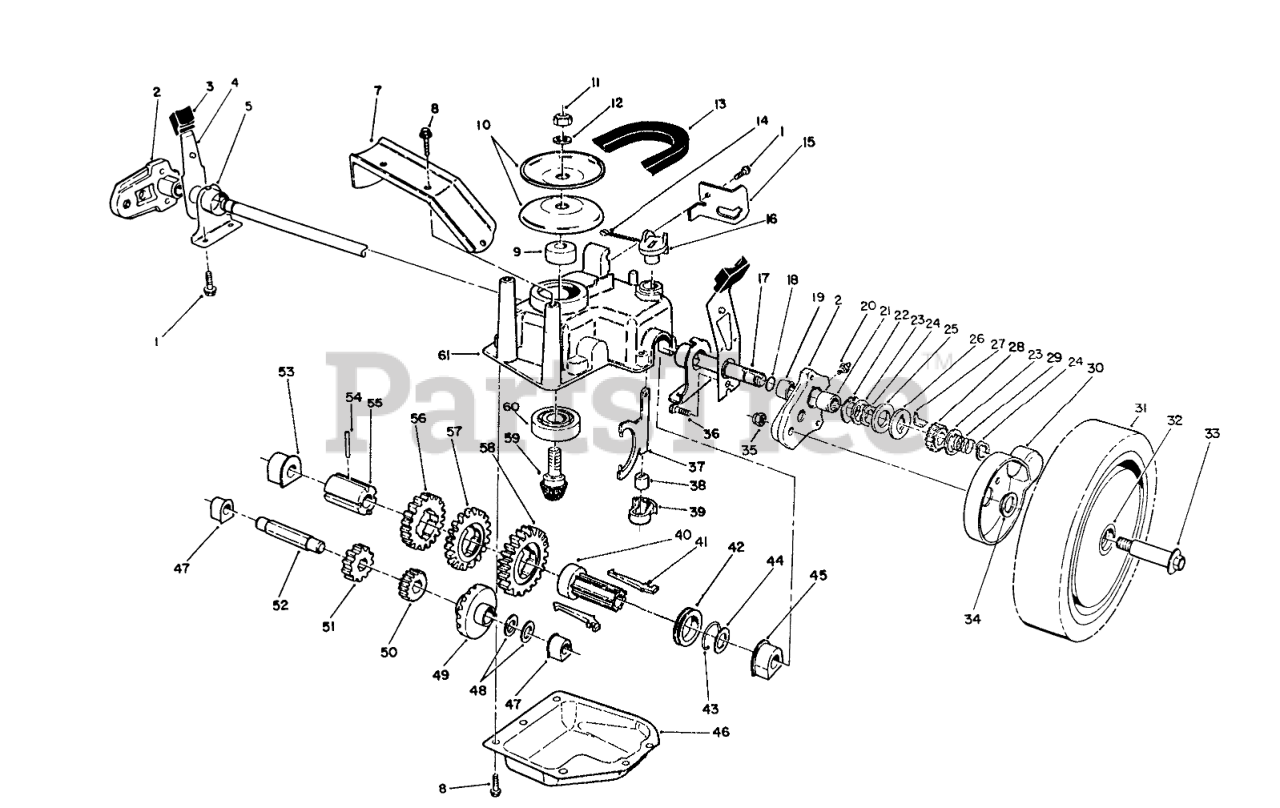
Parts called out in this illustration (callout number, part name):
1	SCREW-HWHTF
2	Pivot Arm Assembly (Incl. Ref. #19-21)
3	KNOB-ARM
4	SPRING ARM ASM
5	CAP-END
7	Bracket-BeltGuide
8	SCREW-HWHTF
9	SPACER
10	Pulley Half
11	NUT-HEX
12	WASHER-FLAT
13	V-BELT
14	PIN-COTTER
15	RETAINER-CABLE
16	LEVER-SHIFT
17	SHAFT-OUTPUT
18	O-RING
19	BUSHING
20	FITTING-GREASE
21	BEARING-ROLLER
22	WASHER-ARM, PIVOT
23	WASHER-THRUST, KEYED
24	RING-CLIP, LOCKING
25	RING-FRICTION
26	WASHER-CLUTCH
27	KEY-ROCKING, LH
28	GEAR-PINION
29	SPRING-COMPRESSION
30	COVER-WHEEL
31	Wheel Tire & Gear Assy. (Incl. Ref. #32)
32	BUSHING
33	WHEEL BOLT
34	SPACER-COVER, WHEEL
35	NUT-LOCK
36	SCREW-HSH, THREAD FORMING
37	YOKE-SHIFT
38	BUSHING-YOKE
39	RETAINER-FORK, SHIFT
40	SLEEVE-KEY, SHIFT
41	KEY-SHIFT
42	COLLAR-SHIFT
43	CLIP-SPRING
44	WASHER-PLAIN
45	BUSHING-OUTPUT
46	Cover-Gearcase
47	BUSHING
48	WASHER-THRUST
49	Gear-Bevel
50	PINION-20T
51	PINION-25T
52	SHAFT-INTERMEDIATE
53	BUSHING
54	PIN-SPRING
55	SLEEVE-GEAR
56	GEAR-39T
57	GEAR-44T
58	GEAR-49T
59	Gear-Pinion
60	BEARING-BALL
61	CASE-GEAR, UPPER
